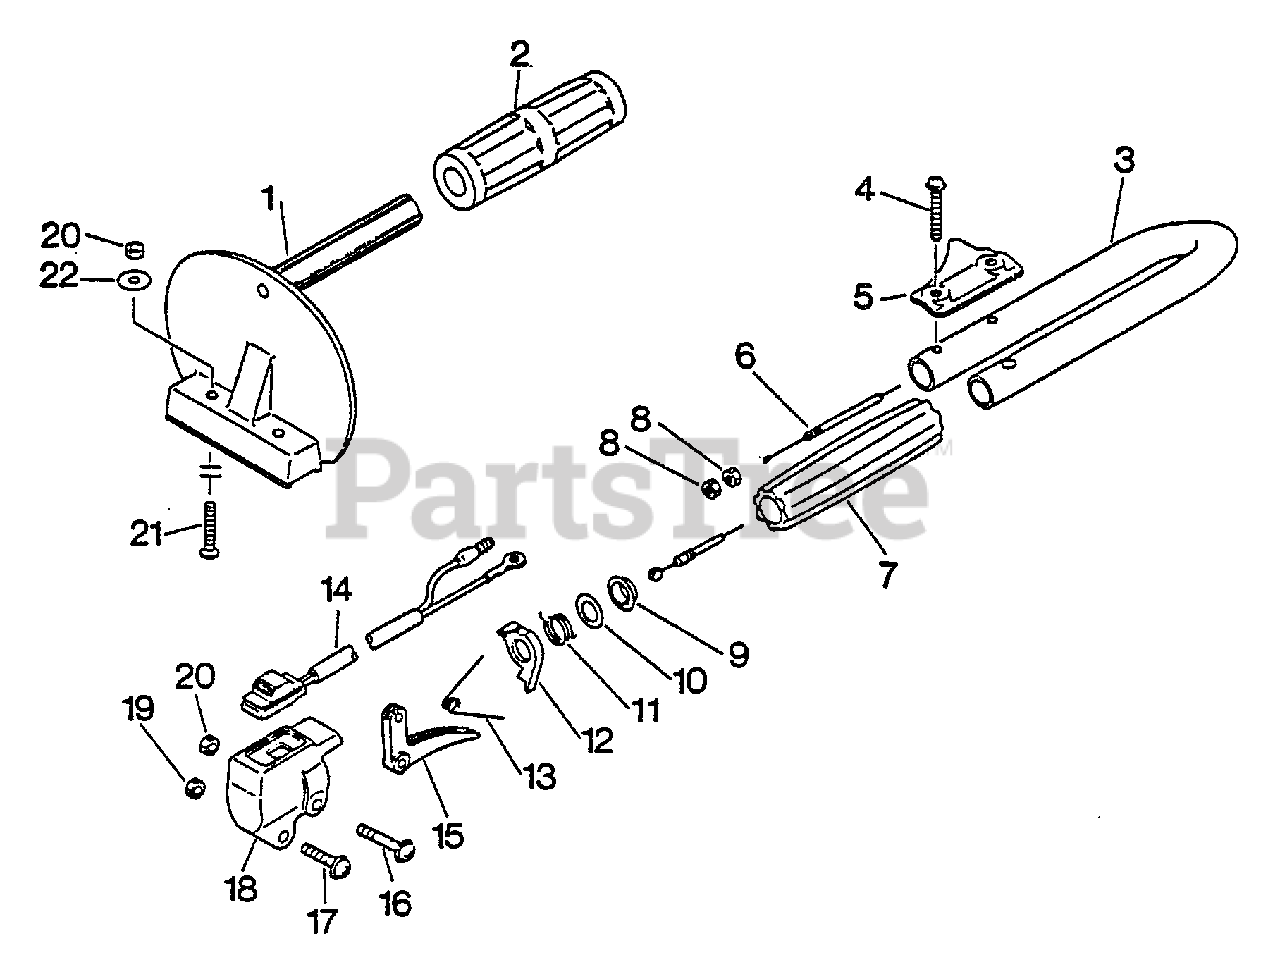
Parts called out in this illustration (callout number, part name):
1	HANDLE - FRONT
2	GRIP, HANDLE
3	HANDLE - REAR
4	SCREW - 5X35
5	BRACKET, HANDLE
6	CABLE, THROTTLE
7	GRIP, HANDLE
10	SPACER
11	SPRING, LOCKOUT LEVER
12	LOCKOUT, THROTTLE
13	SPRING, TRIGGER
14	IGNITION SWITCH ASSY
15	TRIGGER, THROTTLE
16	SCREW - 5X30
17	SCREW - 5X28
18	BRACKET, THROTTLE
20	LOCKNUT - 5
21	SCREW - 5X30
